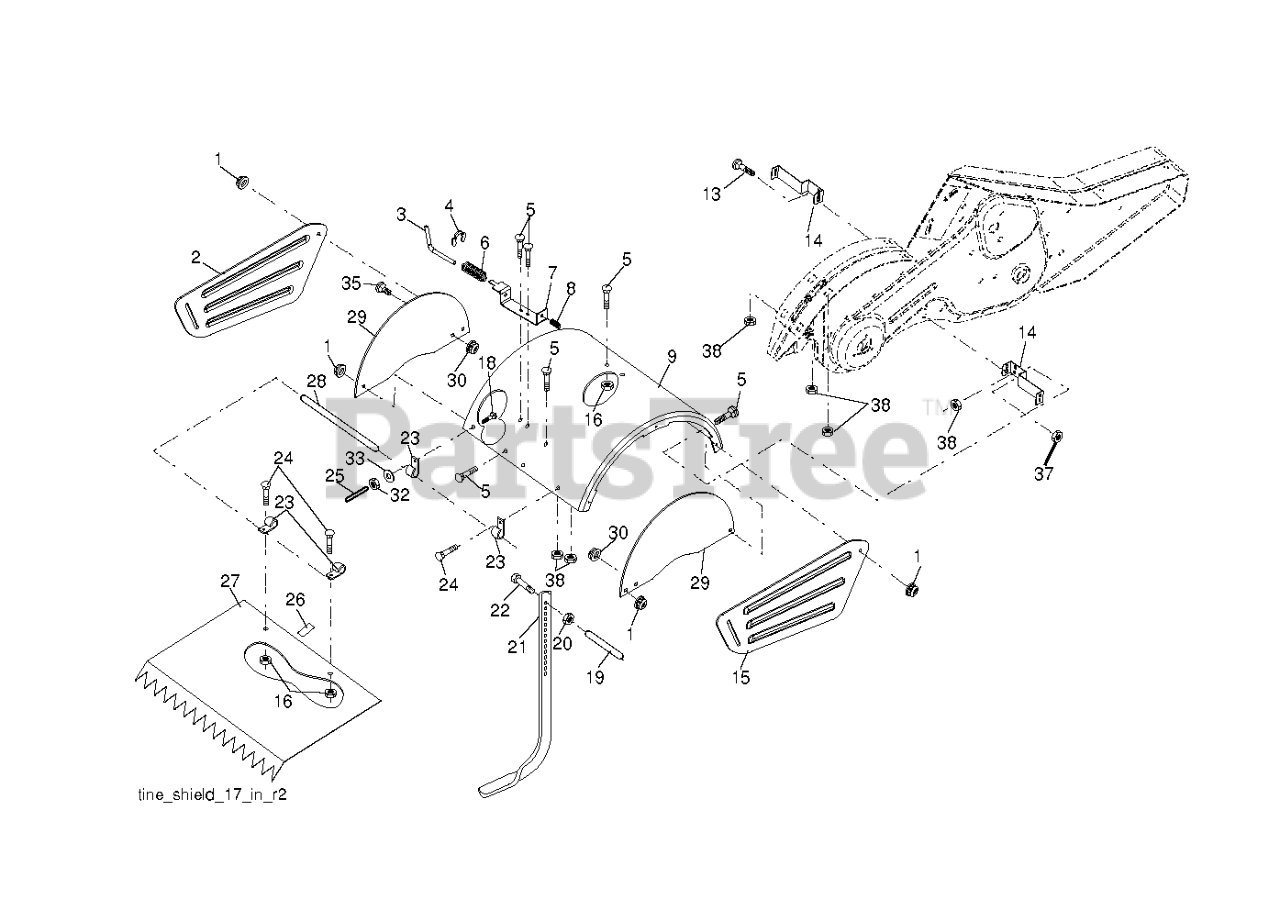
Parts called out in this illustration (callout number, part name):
1	NUT LOCK HEX FLANGE 5/16-18
2	SHIELD.PNT.SIDE.OUTER.LH.ORANG
3	STAKE PIN TI
4	RING, KLIP
5	BOLT, RDHD SQNK 5/16-18 X 3/4
7	BRACKET.LATCH.STAKE.3.20.BLACK
8	SPRING CRT
9	SHIELD.TINE.TILLER.ORANGE
13	BOLT.CARRIAGE.5/16-18
14	BRACKET.TINE.SHIELD.TILLER.BLA
15	SHIELD.SIDE OUTER.RH.ORANGE
16	NUT T
20	NUT.HEX.3/8-16UNC
21	STAKE.DEPTH.16.CRT.BLACK
22	BOLT.375-16
24	BOLT
25	VINYL CAP TI
26	PAD IDLER TI
27	SHIELD.LEVELING.17".ORANGE
28	PIN.HINGE.TILLER
29	SHIELD.TINE.SIDE.ORANGE.TILLER
30	LOCKNUT-FLANGE 5/16-18
32	NUT
33	LOCKWASHER
35	BOLT.CARR.5/16-18X5/8.SHORT
37	NUT.71038.31-18.HEX.NYLOCK
38	NUT
